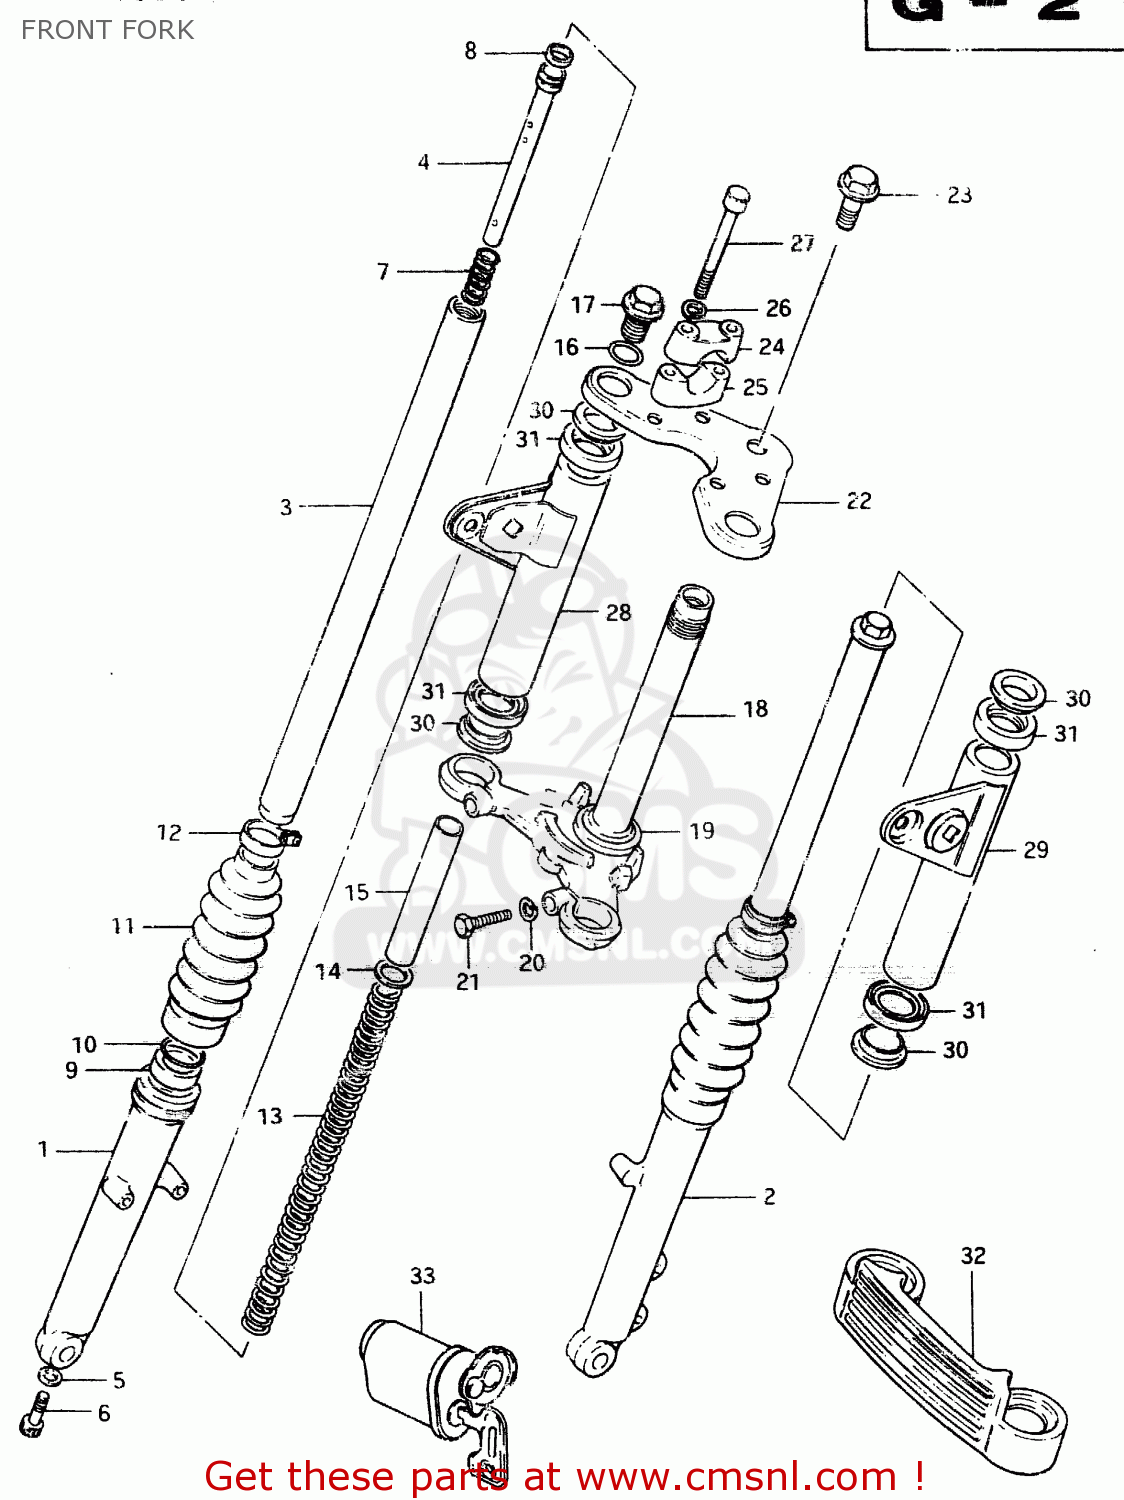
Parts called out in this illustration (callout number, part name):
1	OUTER TUBE, RH
2	OUTER TUBE, LH
3	INNER TUBE
4	CYLINDER
5	GASKET (NAS)
6	BOLT(8X27)
7	SPRING,REBOUND
8	RING,PISTON
9	SEAL,OIL
10	RING,OIL SEAL STOPPER
11	BOOT
12	BAND
13	SPRING
14	JOINT,SPRING
15	SPACER,SPRING
16	O-RING,FORK INNER TUBE
17	CAP
18	STEERING STEM
19	RACE,STEERING OUTER LWR
20	LOCK WASHER
21	BOLT 10X30
22	STEM HEAD, STEERING
23	BOLT
24	HOLDER,HANDLEBAR
25	HOLDER,HANDLE UPR
26	LOCK WASHER
27	BOLT
28	BRACKET, HEADLAMP RH
29	BRACKET, HEADLAMP LH
30	CUSHION
31	GUIDE, COVER
32	COVER
33	LOCK ASSY, STEERING (NEIMAN TYPE EXECUTE
